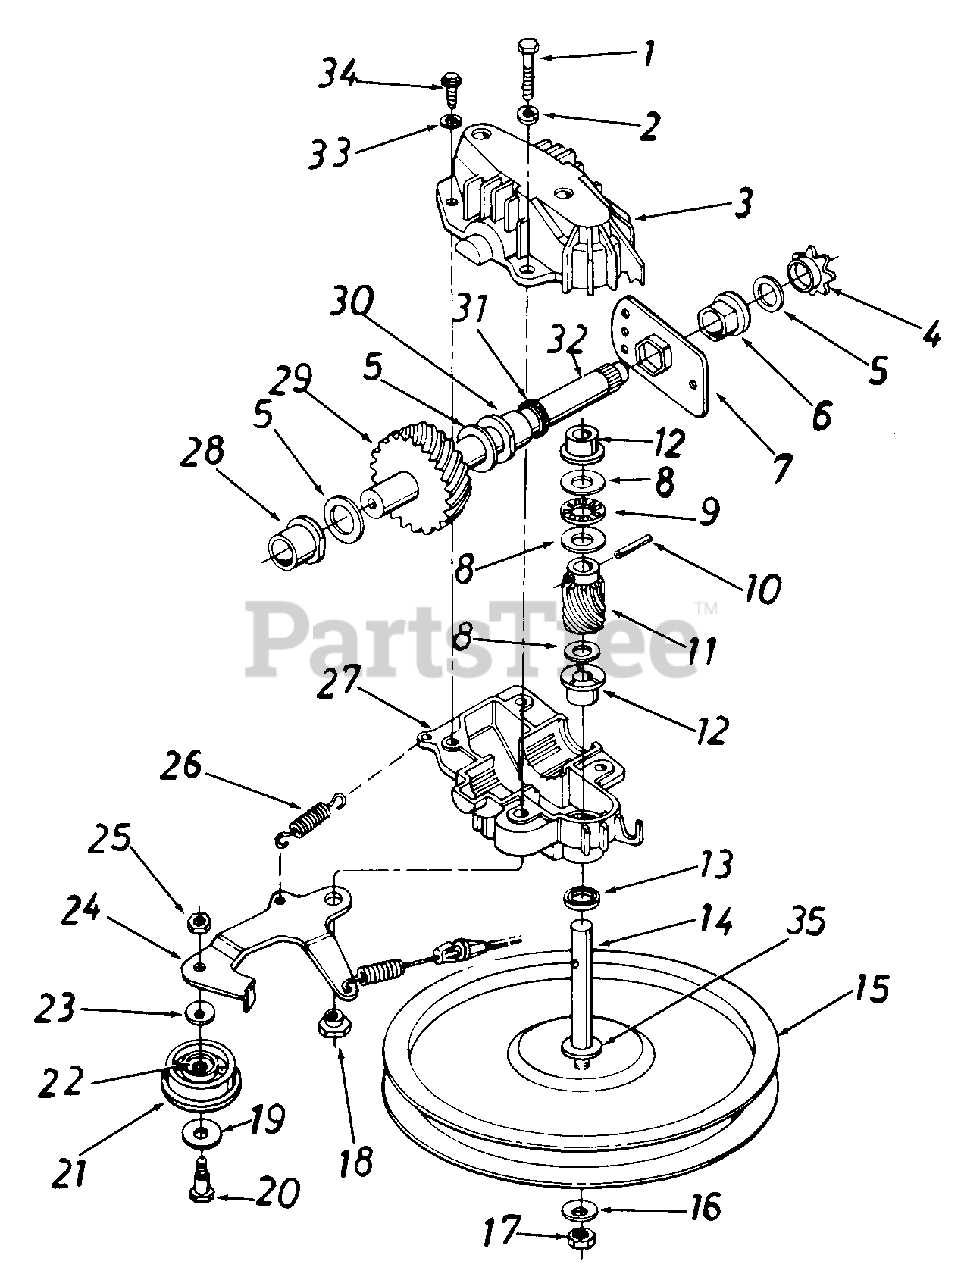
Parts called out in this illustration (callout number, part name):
1	SCREW-HEX 1/4-20 x 1.25
2	LOCK WASHER 1/4 DIA
3	HOUSING HALF-UPPER
4	SPROCKET-7T
5	WASHER-FL
6	BEARING-HEX FLANGE
7	BEARING-CUP HEX
8	WASHER-THRUST.382 x .684
9	BEARING-THRUST
10	PIN-SPRING-SPIR 1/8 x .625
11	GEAR-WORM
12	BEARING-FLANGE
13	SEAL-OIL-.375 ID
14	KIT-TRAN PUL SHFT
15	PULLEY
16	WASHER-SPRING BELL
17	NUT-LH THD-1/4 x 28
18	SPACER-SHLD
19	WASHER-FL .995 x .032
20	SCREW-SHLD
21	KIT-PULLEY
22	BEARING-NEEDLE
23	WASHER-SPRING
24	BRACKET ASSY-IDLER
25	NUT-HEX 1/4-28
26	SPRING-EXTENSION
27	HOUSING HALF-LOWER
28	BEARING-FLANGE
29	SHAFT-ASSY W/GEAR
30	BEARING-FLANGE
32	SHAFT-ASSY W/GEAR
33	WASHER-LOCK-#10
34	SCREW-HEX WASH HD TAP
35	WASHER-HEX
